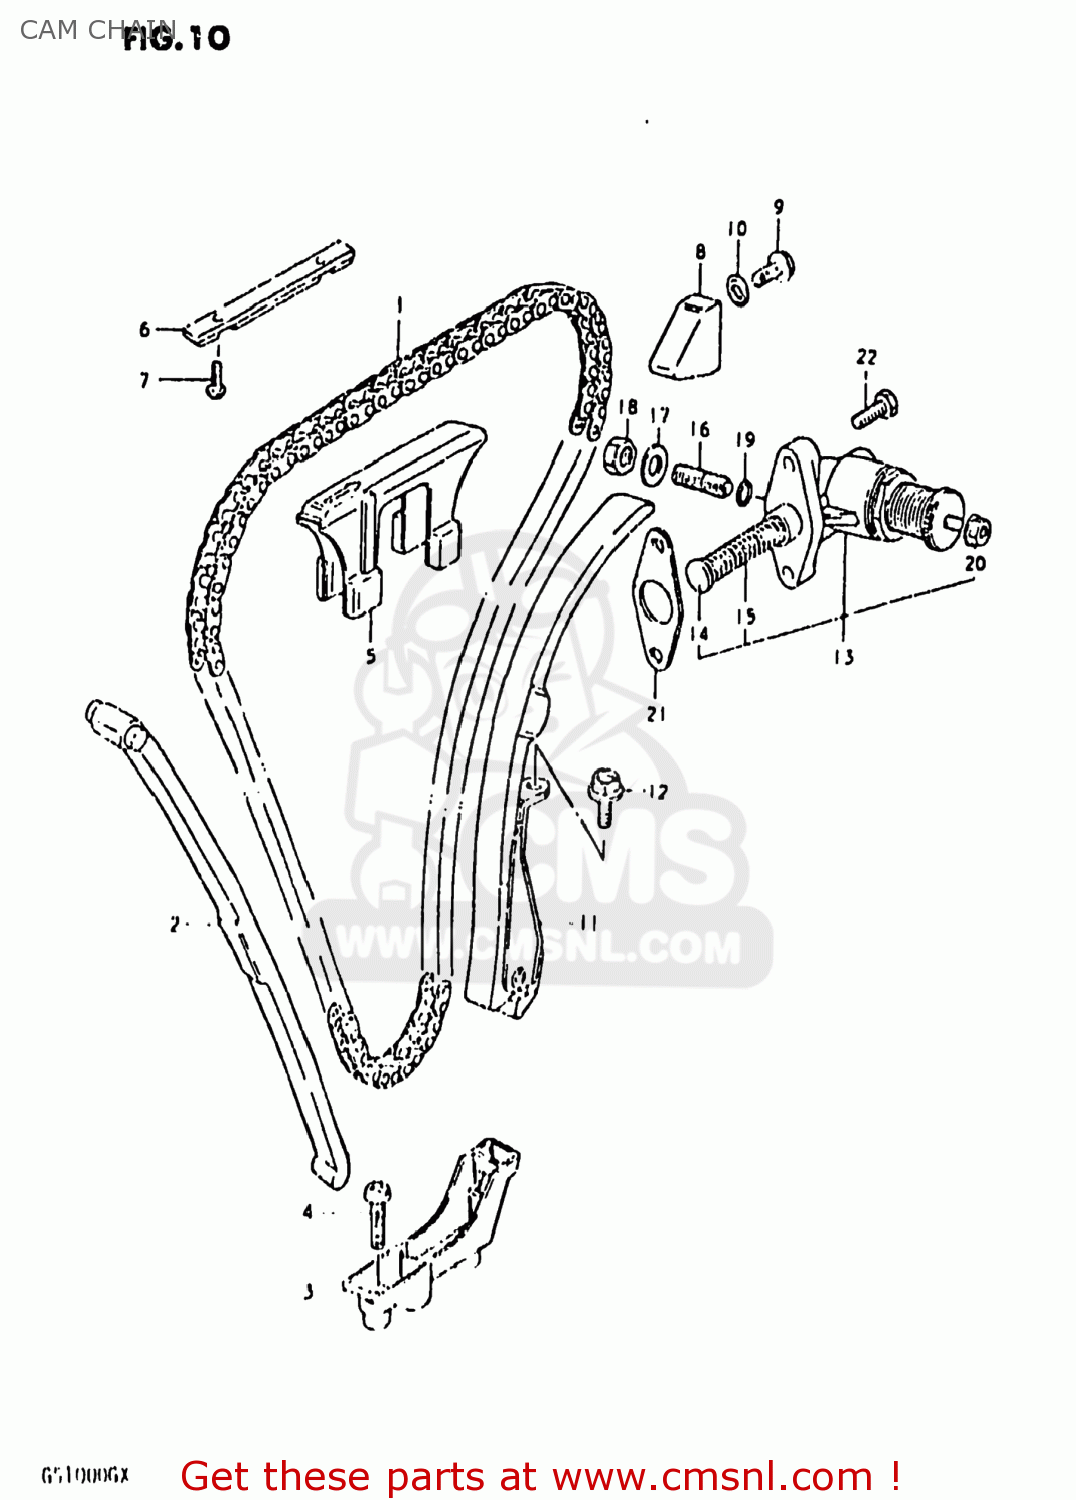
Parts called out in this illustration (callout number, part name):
1	CHAIN,CAMSHAFT DRIVE
2	GUIDE,CAM CHAIN NO.1
3	HOLDER,CAM CHAIN GUIDE
4	SCREW
5	GUIDE,CAM CHAIN NO.2
6	GUIDE,CAM CHAIN
7	SCREW
8	GUIDE,CAM CHAIN
9	BOLT
10	GASKET (NAS)
11	TENSIONER,CAM CHAIN
12	BOLT
13	ADJUSTER ASSEMBLY,TENSIONER
14	ROD,PUSH
15	SPRING
16	SCREW
17	WASHER
18	NUT
19	O-RING
20	NUT
21	GASKET,TENSIONER ADJUSTER (MCA)
22	SCREW (6X25)
